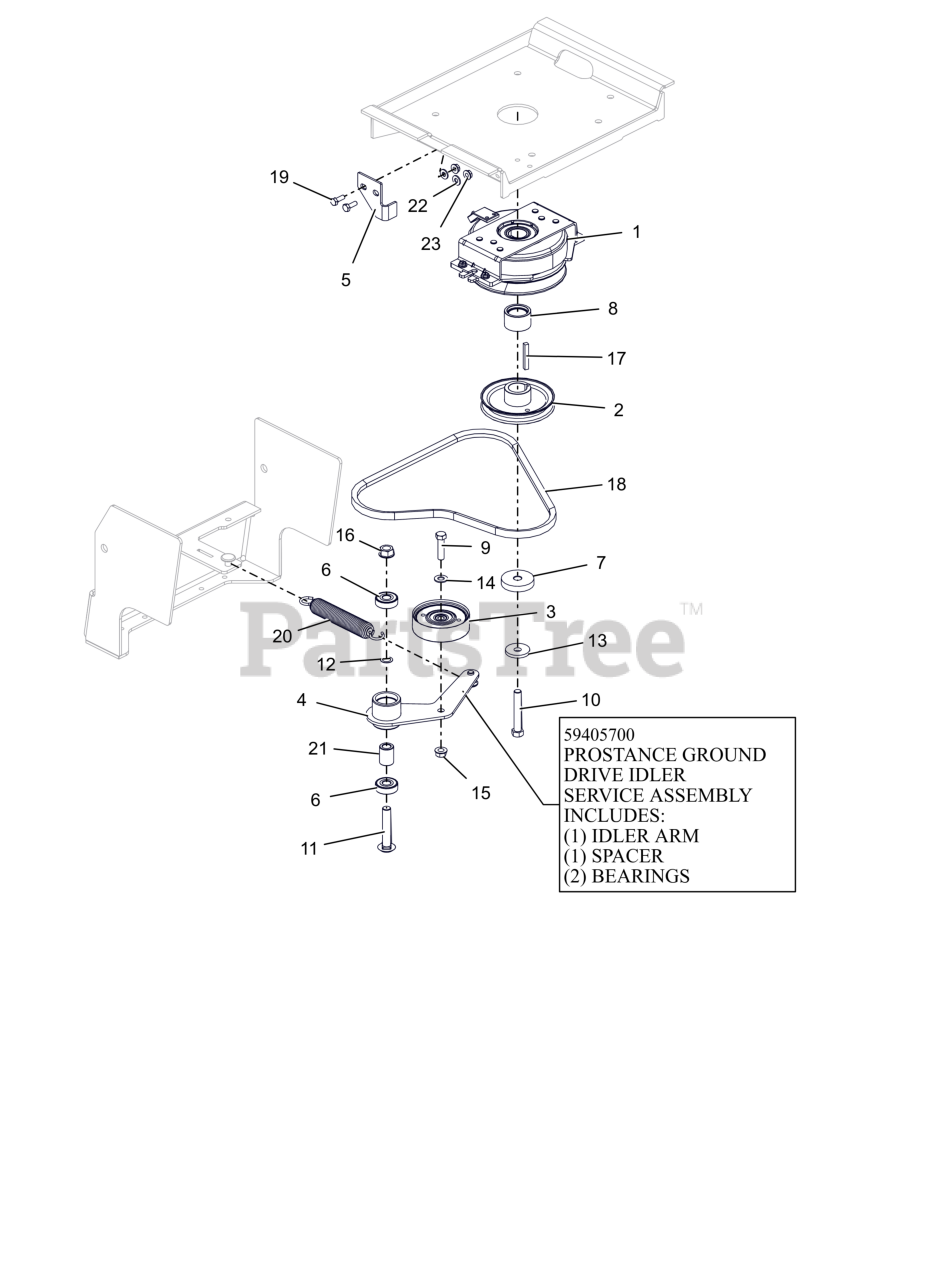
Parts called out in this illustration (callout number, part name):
1	CLUTCH, OGURA GT2.75-BBO1
2	SHEAVE, ENGINE 4.50 OD x 1.127 ID (BLACK)
3	IDLER, FLAT 3.5" NO FLANGES
4	WLDMT, IDLER ARM
4	PROSTANCE GROUND DRIVE IDLER SERVICE ASSEMBLY
5	BRKT, CLUTCH STOP (BLACK)
6	BRG-BALL .500X1.38X.437
7	SPACER, .450X2.00X.396
8	SPCR, CLUTCH
9	BLT, HEX .38-16X1.50 G5 ZCC
10	BLT, HEX 0.4375-20X2.75 G8 ZCC NT
11	BTL,RHSSN .500-13 X 2.75 G5 ZCC
12	WASHER, .500X.750X.020 THRUST
13	WASHER, 7/16" SPRING DISK
14	WSHR,FLT .406X.812X.065 ZCC
15	NUT-LK-CTR-FLG .375-16 GF ZCC
16	NUT-LK-CTR-FLG .500-13 GG ZCC
17	KEY-STR .25X1.75X.25
18	V-BELT, A -RAW EDGED LAMINATED
19	BLT, HEX .25-20X.75 G5 ZCC
20	SPRING, EXTENSION 1.0 X 6.65
21	SPACER .510 X .867 X 1.1485
22	WSHR,FLT .281X.625X.065 ZCC
23	NUT-LK-TOP-FLG .250-20 GF ZCC
